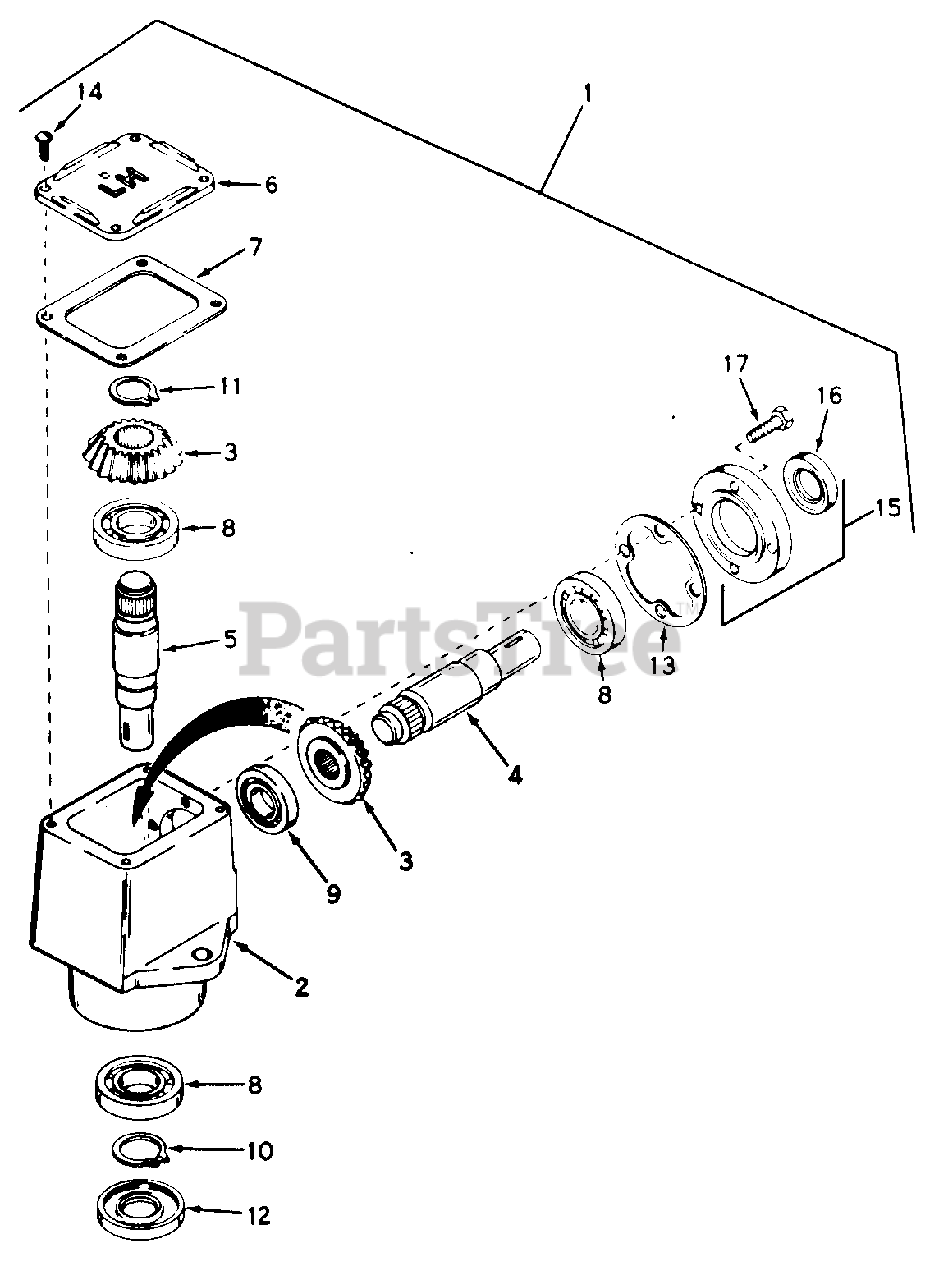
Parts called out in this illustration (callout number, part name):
1	Head Ass'y., L.H.
2	Housing, Right angle drive
3	Gear, Miter
4	Shaft, Input
5	Shaft, Output
6	Cover, Left hand
7	Gasket, Cover
8	Bearing, Ball
9	Bearing, Ball
10	Ring, Snap
11	Ring, Snap
12	Seal, Oil
13	Gasket, Cap
14	Screw, Rd. Hd. Self Tap, 10-24 x 1/2
15	Cap & Seal Ass'y., Retainer-
16	Seal, Oil
17	Screw, Hex Hd. 1/4-20 x 1
